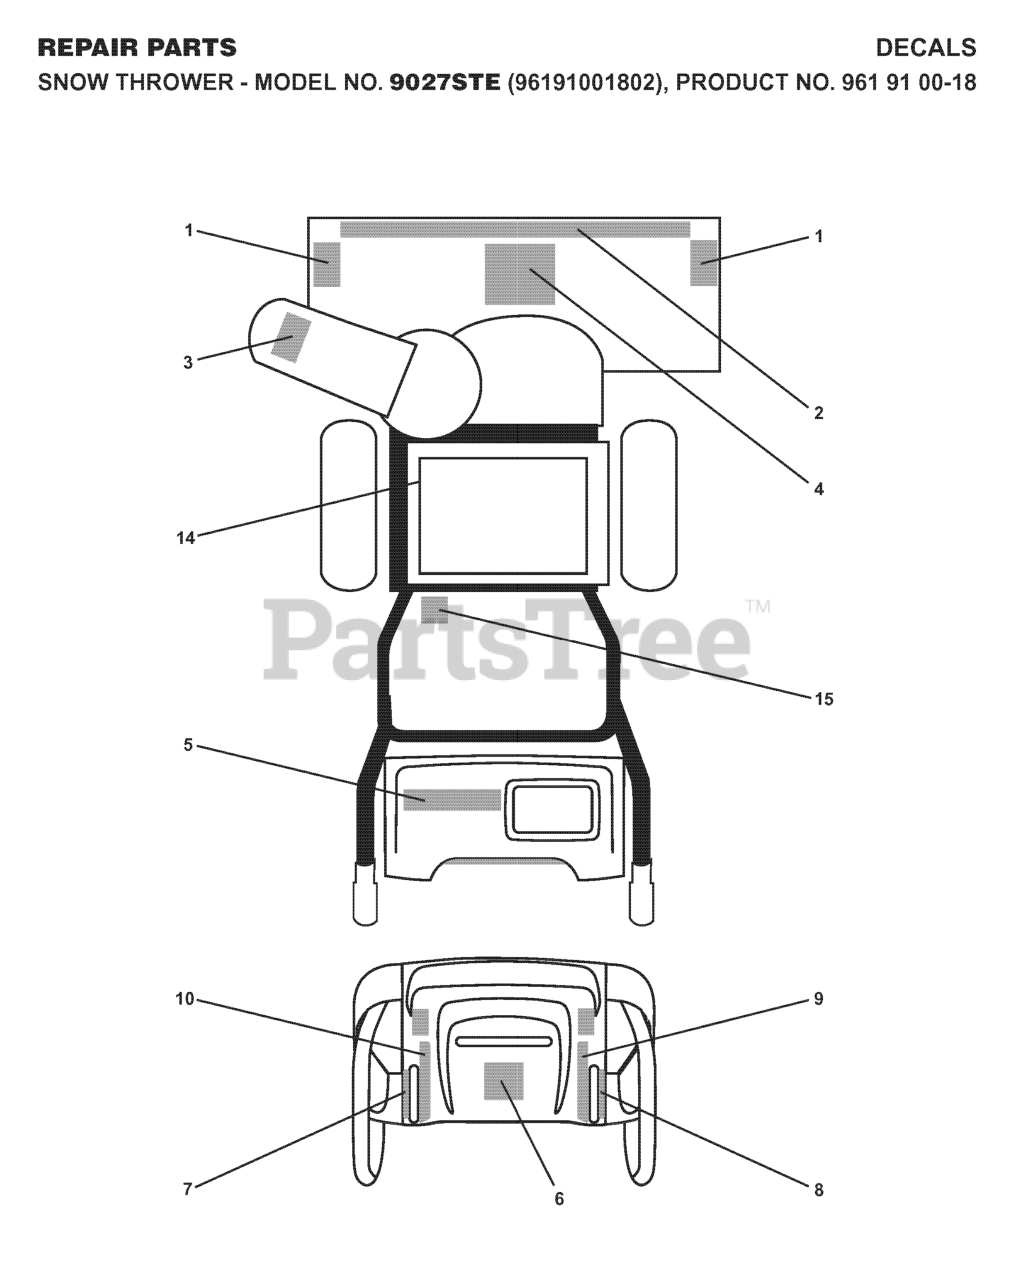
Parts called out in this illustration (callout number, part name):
1	DECAL.AUGER.SAFETY.
3	DECAL.CHUTE.SAFETY.
4	DECAL.AUGER."
6	DECAL.CONSOLE.INSTRUCTION
7	DECAL.POWER.STEER.LT.TRIG.INT
8	DECAL.POWER.STEER.RT.TRIG.INT
10	DECAL.REM.DEFLECTOR.LT
14	DECAL.BELT.GUARD.
15	DECAL.FENDER
